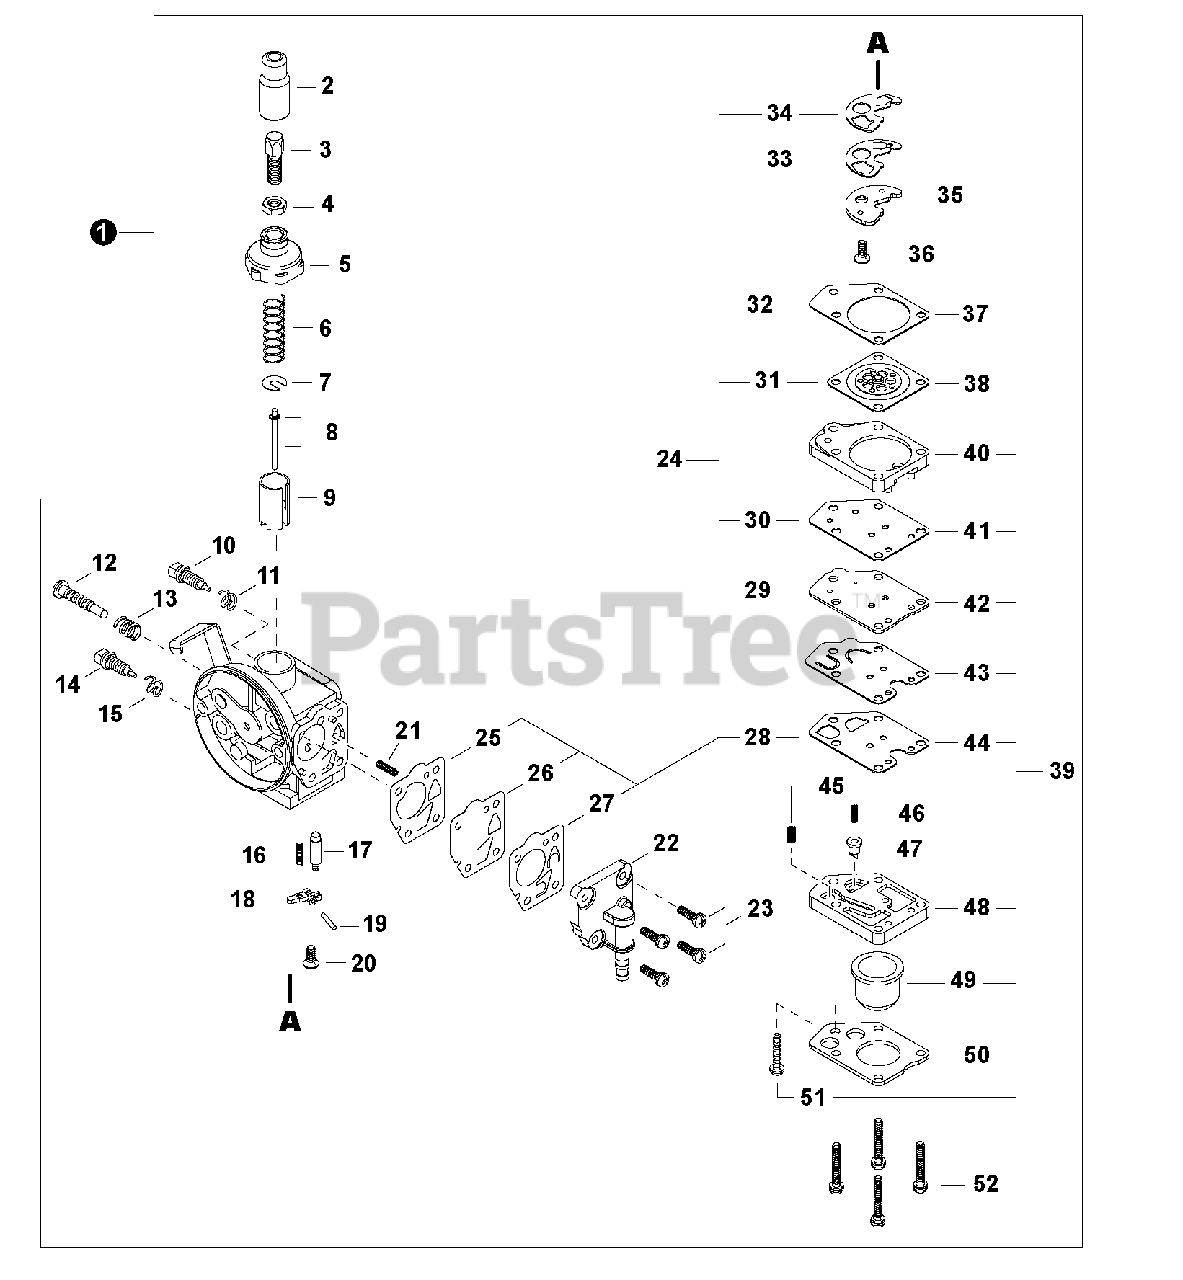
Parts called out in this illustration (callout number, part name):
1	CARBURETOR - DPV10W-18D
3	ADJUSTER, CABLE
4	NUT, LOCK
5	CAP, CARBURETOR
7	WASHER, SPRING SUPPORT
8	NEEDLE, JET
9	VALVE, THROTTLE
10	SCREW, SLOW AIR
12	SCREW, IDLE ADJUST
14	SCREW, MAIN ADJUST
16	SPRING, TENSION
17	VALVE, INLET NEEDLE
18	LEVER, METERING
19	PIN, METERING LEVER
20	SCREW M3×8
21	SPRING, COIL
22	PUMP BODY
24	GASKET / DIAPHRAGM KIT
25	GASKET, DIAPHRAGM
26	DIAPHRAGM, METERING
27	VALVE, PUMP
28	VALVE, CHECK
31	DIAPHRAGM, METERING
32	GASKET, METERING DIAPHRAGM
33	VALVE, CHECK
34	PACKING
36	SCREW M3×8
37	GASKET, METERING DIAPHRAGM
38	DIAPHRAGM, METERING
39	PURGE PUMP KIT
40	COVER, PUMP
43	PLATE, PUMP
44	VALVE, CHECK
47	VALVE, CHECK
48	BODY, PURGE
49	BULB, PURGE
50	RETAINER, PURGE BULB
52	SCREW 3×20
